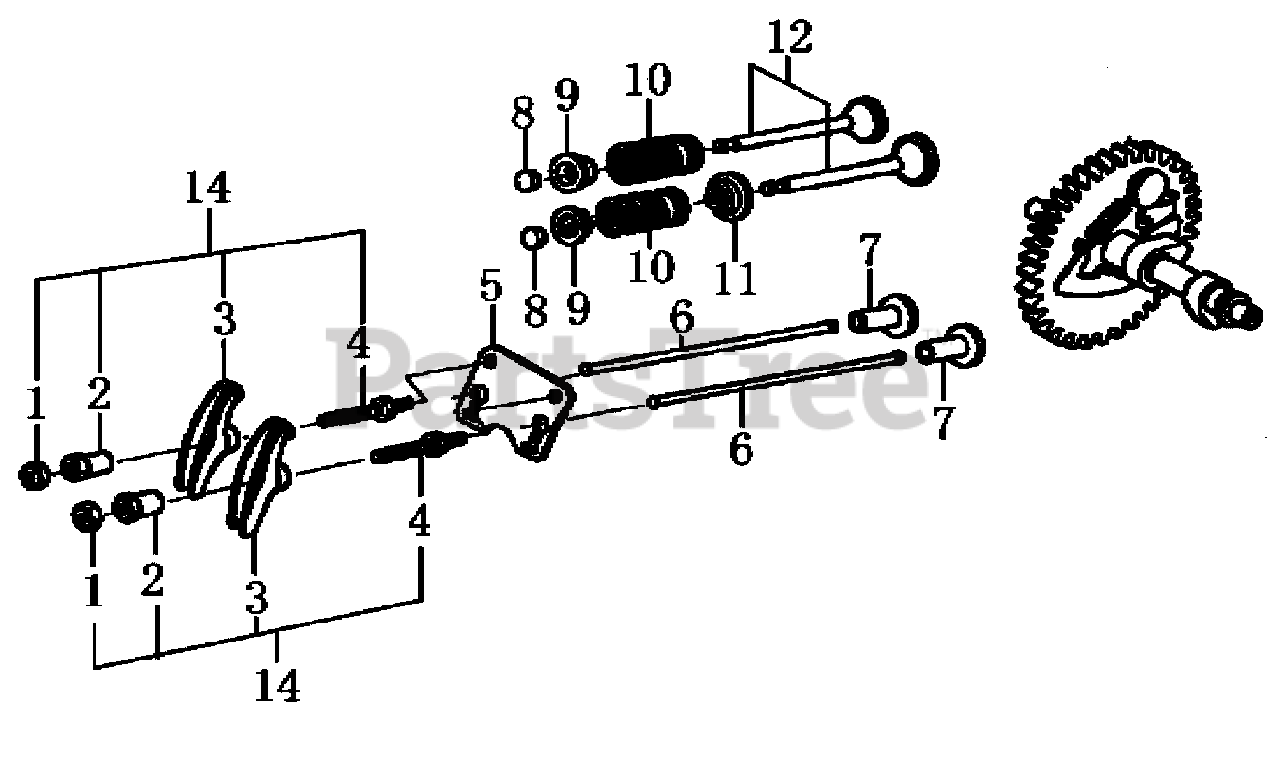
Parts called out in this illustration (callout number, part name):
1	NUT, PIVOT ADJUSTING
2	PIVOT, ROCKER ARM
3	ARM, VALVE ROCKER
4	BOLT, PIVOT, ARM
5	PLATE, PUSHROD GUIDE
6	ROD, PUSH
7	LIFTER, VALVE
8	ROTATOR, VALVE
9	RETAINER, VALVE SPRING
10	SPRING, VALVE
11	SEAL, GUIDE
14	ARM ASSY.
